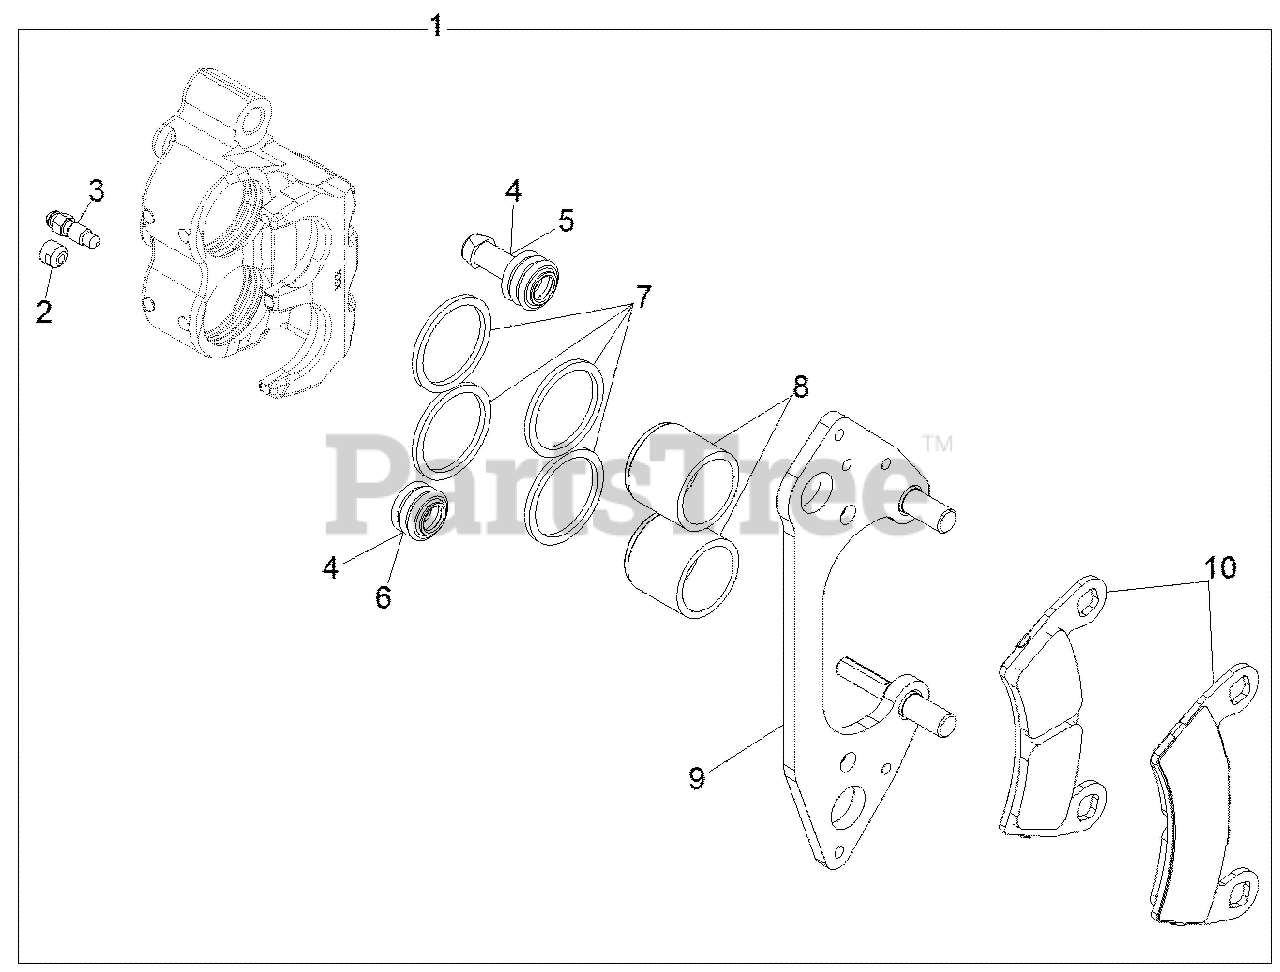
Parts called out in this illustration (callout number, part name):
1	ASM-BRK-CAL-L-DB1-3/8-GROOVED
1	ASM-BRK-CAL-R-DB1-3/8-GROOVED
2	SCR-M10X1.0X8,SOC SET-OD
3	SCR-M7X1.0,BLEEDER,OLIVE D
4	KIT,BOOT,FRONT BRAKE
5	BOOT-PIN BUSHING
6	BOOT-PIN SEAL
7	SEAL-CALIPER,INNER,1.375"
8	PISTON-BRAKE,1.375,AL,GROOVED
9	ASM., CALIPER, MOUNT, FRONT
10	KIT-ASM,PAD,BRAKE,DB,1.375
